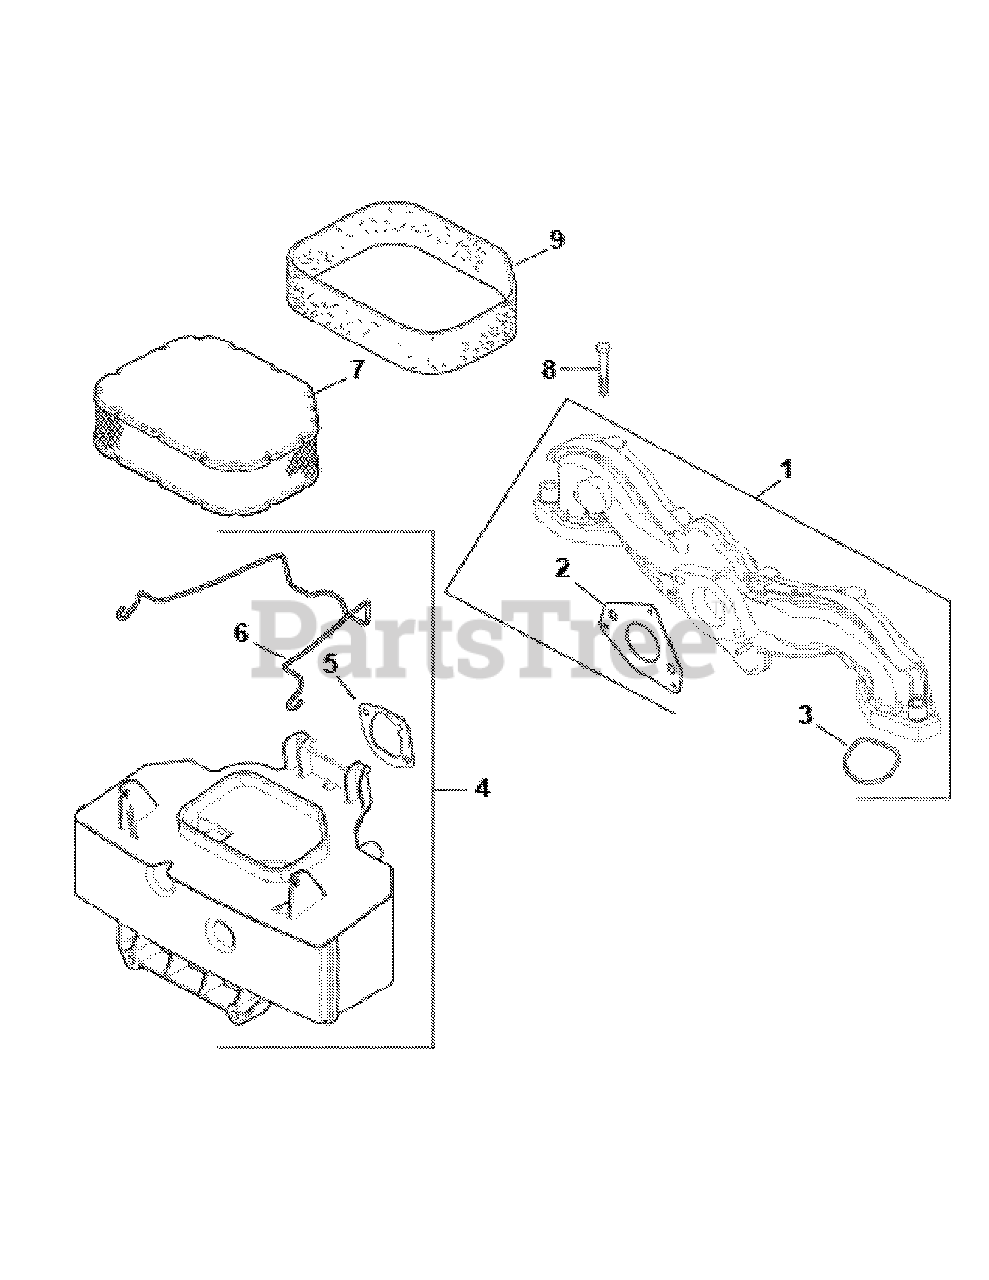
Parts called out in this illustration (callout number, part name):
1	Intake Manifold
2	Carburetor Gasket
3	Intake Port O-Ring
4	Air Cleaner Base
5	Air Cleaner Base Gasket
6	Air Cleaner Element Latch
7	Air Filter Element
8	Hex Flange Screw
9	Pre Filter
